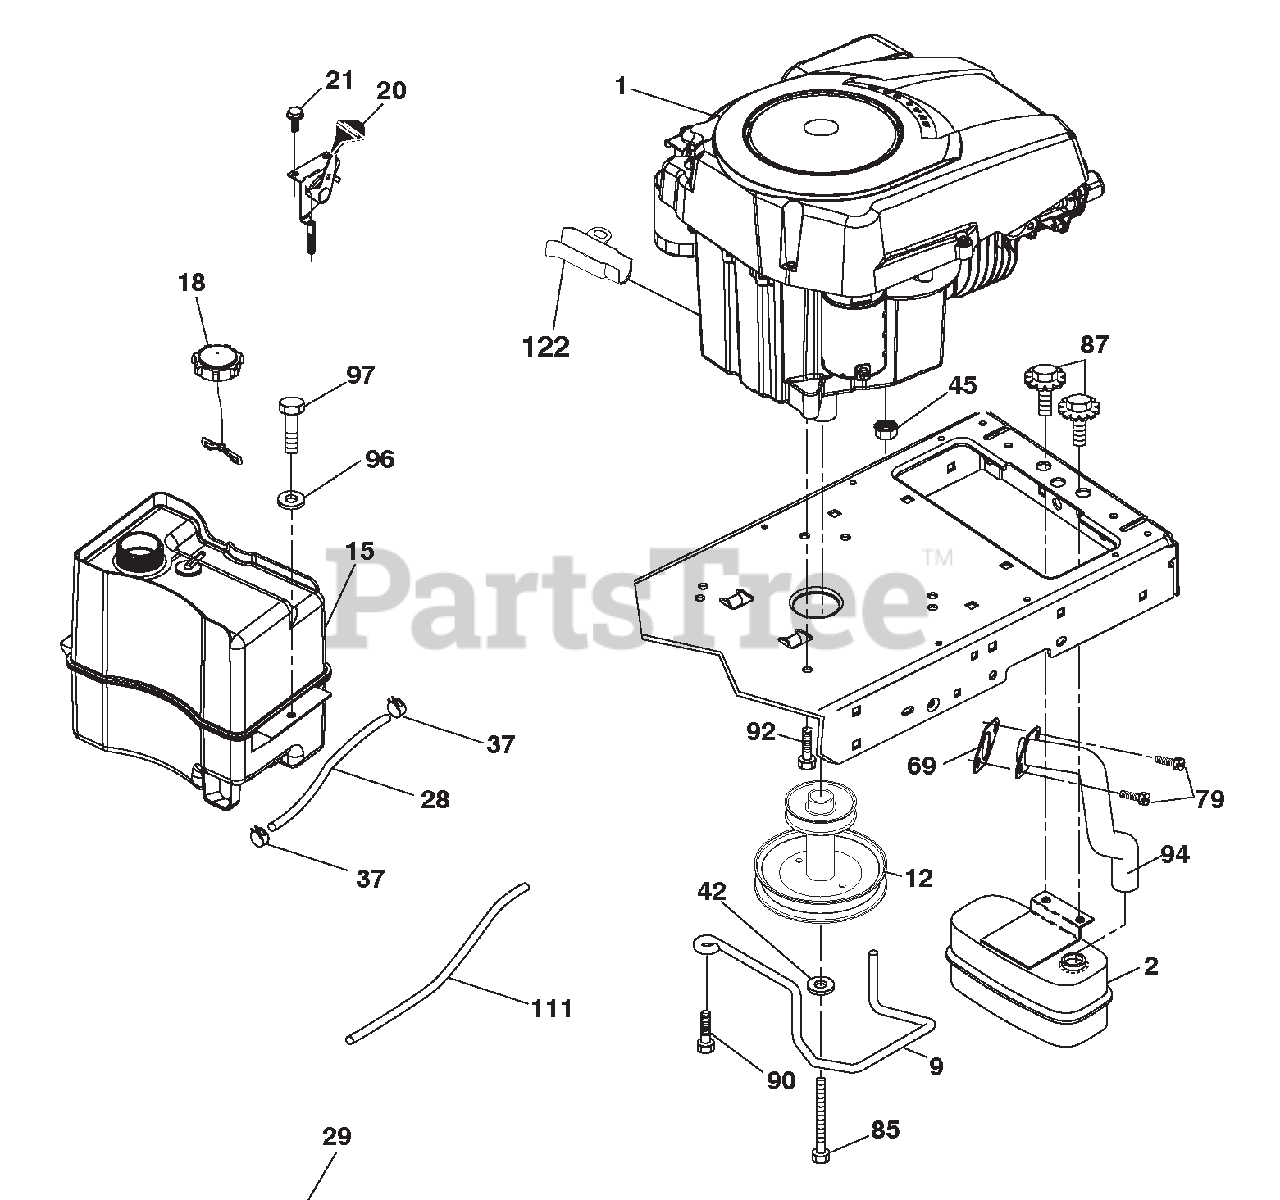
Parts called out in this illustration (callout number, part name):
1	3230 (445326)(ORDER PARTS FROM
1	ENGINE MANUFACTURER.)
2	MUFFLER.SINGLE.CYL.KOHL.COURAG
9	KEEPER BELT ENGINE
12	PULLEY.ENGINE
15	TANK.FUEL.2.5.GAL.
18	CAP.FUEL
20	CONTROL THROTTLE/CHOKE
28	LINE.FUEL.20"
29	KIT.SPARK ARRESTOR(392390 B&S)
37	CLAMP.HOSE.BLK.
42	WASHER.LOCK.HVY HLCL.SPR.7/16
45	Nut, Keps Hex 1/4-20 unc
69	GASKET.KOHLER.SV.I.
79	SCREW.SOCKET HD.5/16-18 X .75
85	BOLT.HEX.7/16-20X4XGR5-1.5THR.
87	BOLT.5/16-18UNCX3/4 W/SEMS.BLK
90	SCREW.3/8-16X1.SMGML.TAP/R.BLK
92	SCREW.3/8-16X1.SMGML.TAP/R.BLK
94	TUBE.EXHAUST.KOHL.COURAGE
96	WASHER.9/32 X 7/8 X 16GA.
97	SCREW.HEXWSH.THDROL.1/4-20X3/4
111	PURGE.LINE.CARB
122	Extension Drain Oil
